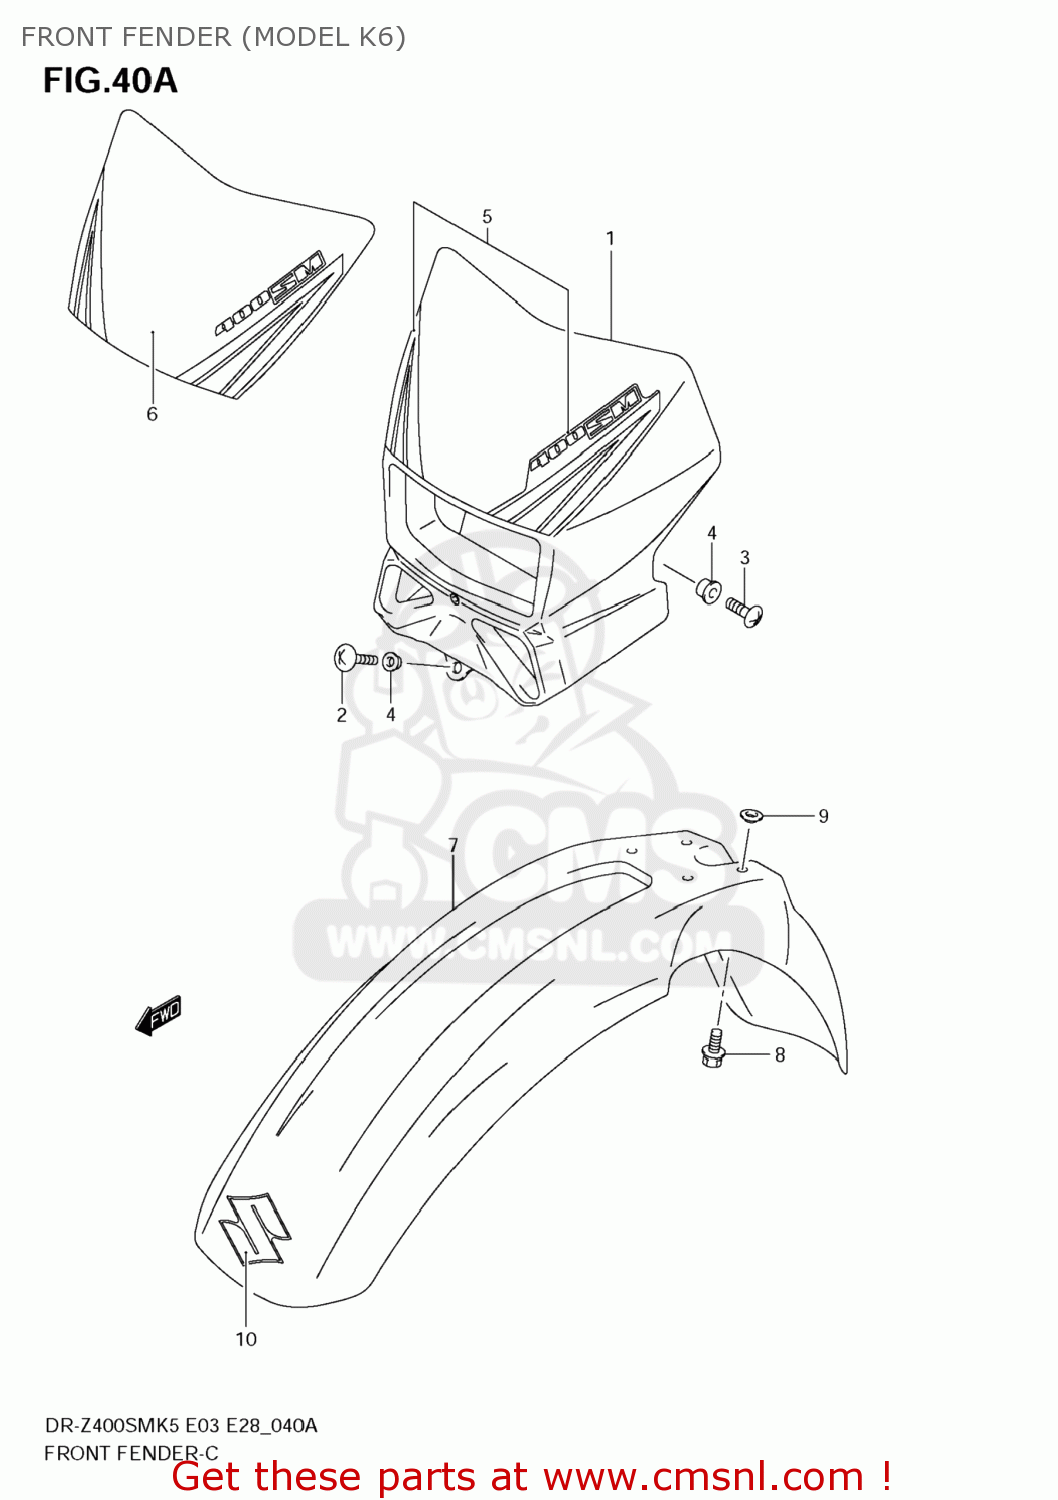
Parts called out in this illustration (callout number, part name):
1	COVER,HEADLAMP
2	SCREW
3	SCREW
4	WASHER
5	TAPE SET,HEADLAMP HOUSING
6	TAPE,HEADLAMP HOUSING
7	FENDER,FR
8	BOLT(6X16)
9	WASHER
10	EMBLEM,S
